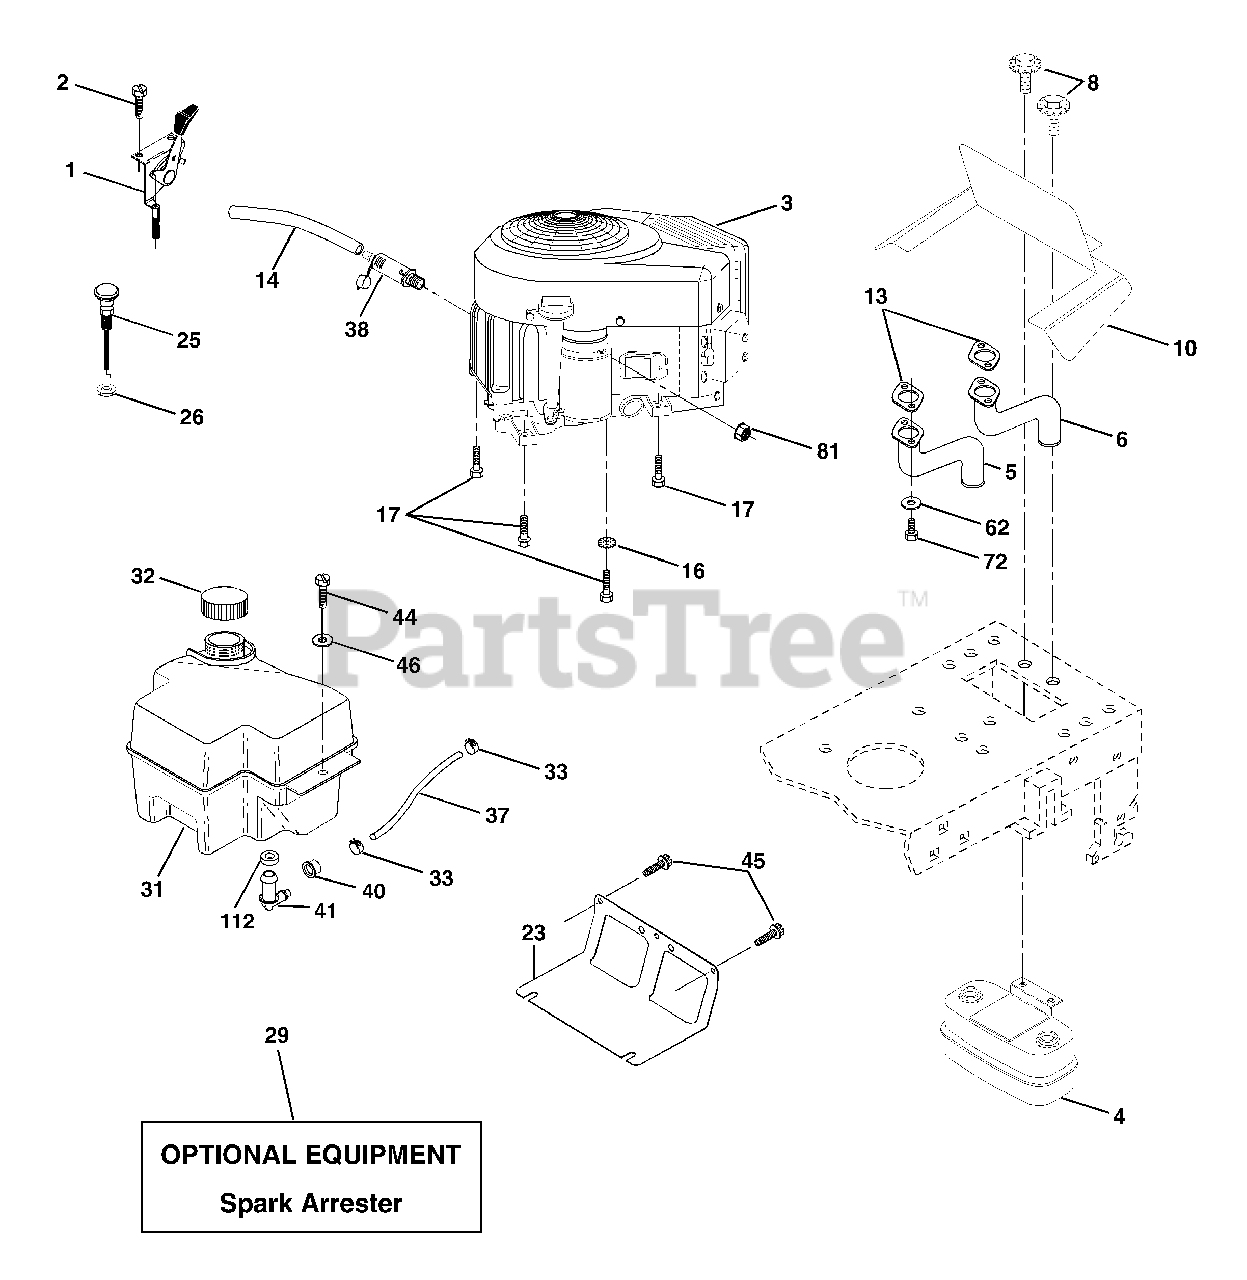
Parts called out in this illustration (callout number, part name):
1	Control Th/ch Flag
2	Screw Hex Thd Cut 1/4-20x1/2
4	Muffler Exhaust
5	Exhaust Tube LH
6	Exhaust Tube RH
8	Bolt 5/16-18 UNC x 3/4
10	Shield Browning
13	Gasket Muffler
14	Tube Drain Oil Easy
16	Washer Lock Ext Tooth 3/8
17	Screw 3/8-16 x 1-1/2
23	Shield Brn/Dbr Guard
25	Control Choke
26	Nut Keps 3/8-24 Unf
29	Arrestor Spark
31	Tank Fuel Front 2 00
32	Cap Fuel
33	Clamp Hose Black
37	Line Fuel 20"
38	Plug Oil Drain Easy
41	Stem Tank Fuel
44	Screw Hex wsh Thdrol 1/4-20x3/4
45	Screw Hex Wsh Thdrol 3/8-16 x 3/4
46	Washer 9/32 X 7/8 X 16 Ga
62	Washer Lock 5/16
72	Screw Hex 5/16-18 x 3/4
81	Nut Keps Hex 1/4-20 Unc
112	Bushing
